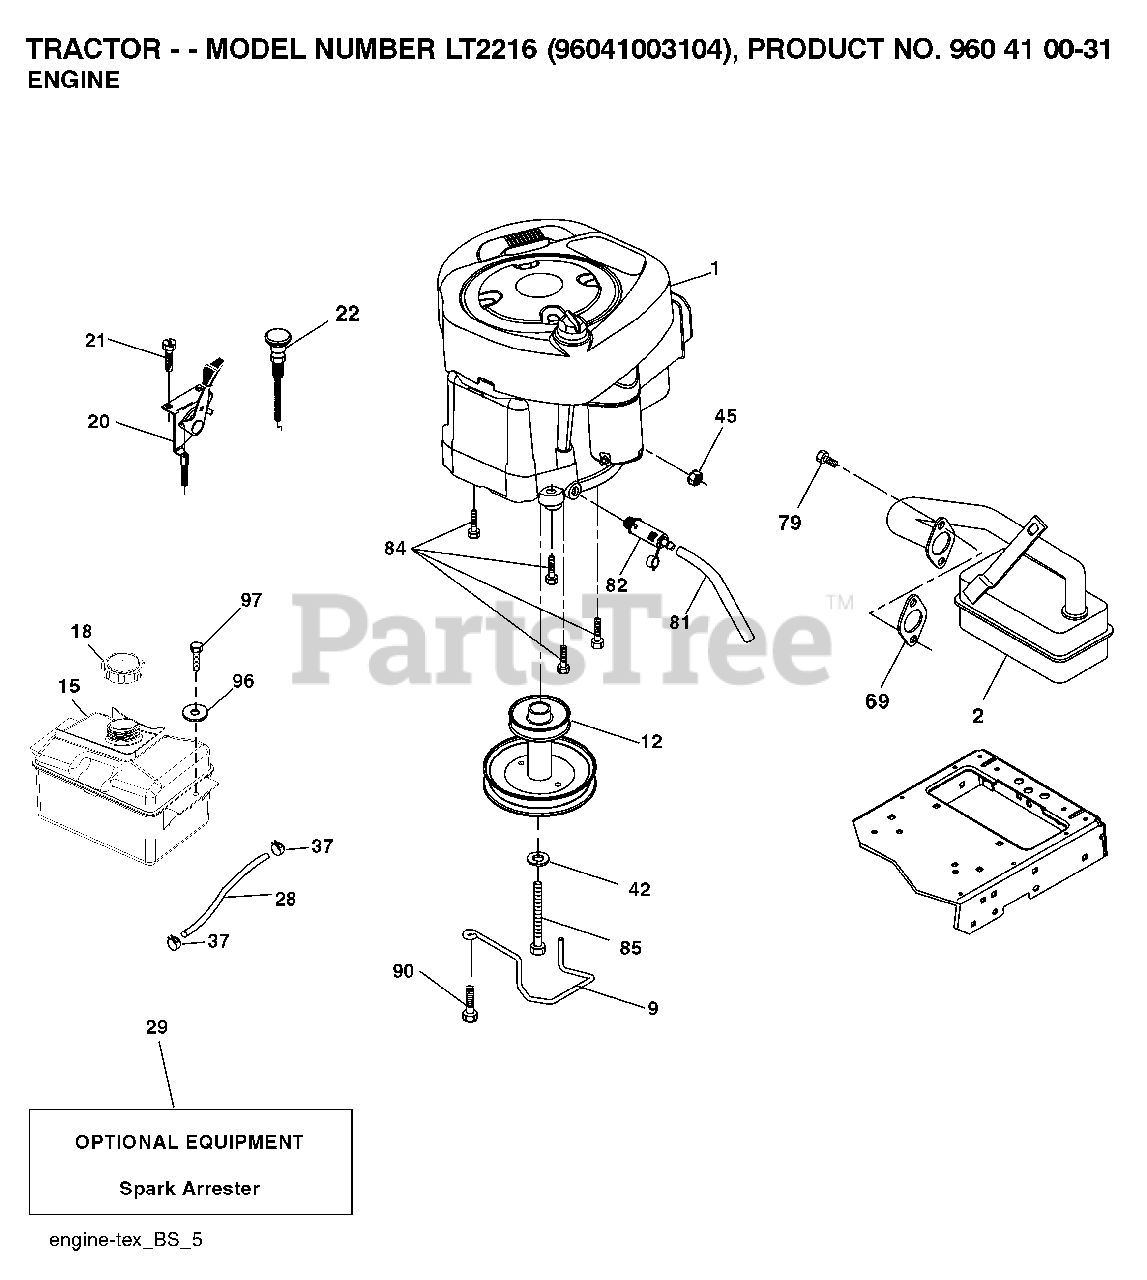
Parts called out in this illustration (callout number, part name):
9	KEEPER.BELT.ENGINE.3.25
12	PULLEY ENGINE
15	TANK FUEL FRT 1.5 GAL
18	FUEL CAP
20	CONTROL.TH/CK.C.
21	SCREW
28	LINE.FUEL.20
29	ARRESTER SPARK (OPTIONAL)
37	HOSE CLAMP
42	LOCKWASHER
45	NUT
69	REPL BY 532 27 22-93
79	SCREW.SOCKET HD.5/16-1
81	TUBE, DRAIN OIL ASM.
82	PLUG DRAIN OIL EASY
84	SCREW.3/8-16
85	BOLT HEX 7/16-20X4-1/4"
90	SCREW 3/8-16X1
97	SCREW HEXWSHR 1/4-20X3/4
